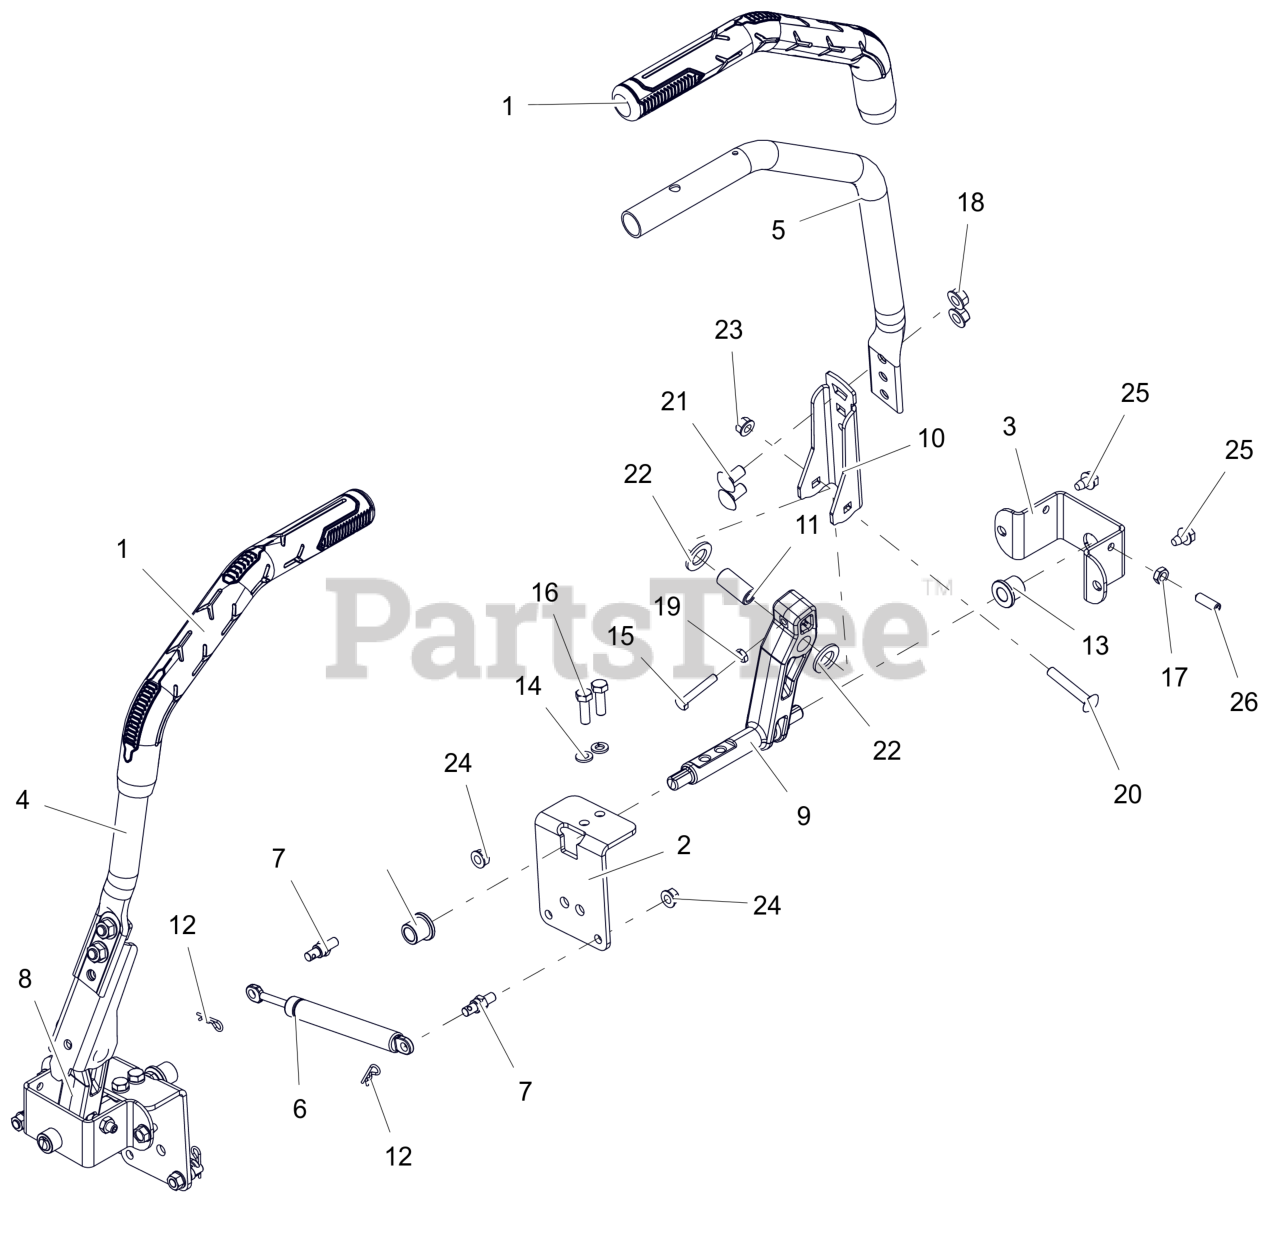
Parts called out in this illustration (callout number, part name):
1	GRIP, ARIENS HANDLEBAR
2	BRKT, STEEERING
3	BRKT, STEERING
4	HANDLE, STEERING-RH
5	HANDLE, STEERING-LH
6	DAMPER, STRAIGHT MOUNT
7	COUPLER, DAMPER MOUNT
8	ARM- STEERING-RH LOWER (MACH)
9	ARM- STEERING-LH LOWER (MACH)
10	ARM, CONTROL UPPER
11	BSHG-SLV .342 X .627 X 1.331
12	PIN, HAIR #213 .08X1.19 ZCC
13	BHSG-FLG .500X.750X.750X.125
14	WSHR,LK-REG .312X.078 ZCC
15	BLT, HEX .25-20X1.50F G5 ZCC
16	BLT, HEX .31-18X1.00 G8 ZCC
17	NUT-JAM .312-18 G2 ZCC
18	NUT-LK-CTR-FLG .375-16 GF ZCC
19	NUT-JAM .250-20 G2 ZCC
20	BLT, RHSSN .31-18X2.00 G5 ZCC
21	BTL,RHSSN .375-16 X 0.75 G5 FPB
22	WSHR, FRICTION
23	NUT,LK-CTR-FLG .31-18 GF ZCC
24	NUT-LK-TOP-FLG .312-18 GF ZCC
25	SCR,TAP .312-18X.50 HWH TR ZCC
26	SCR-SET, .312-18X1.000
